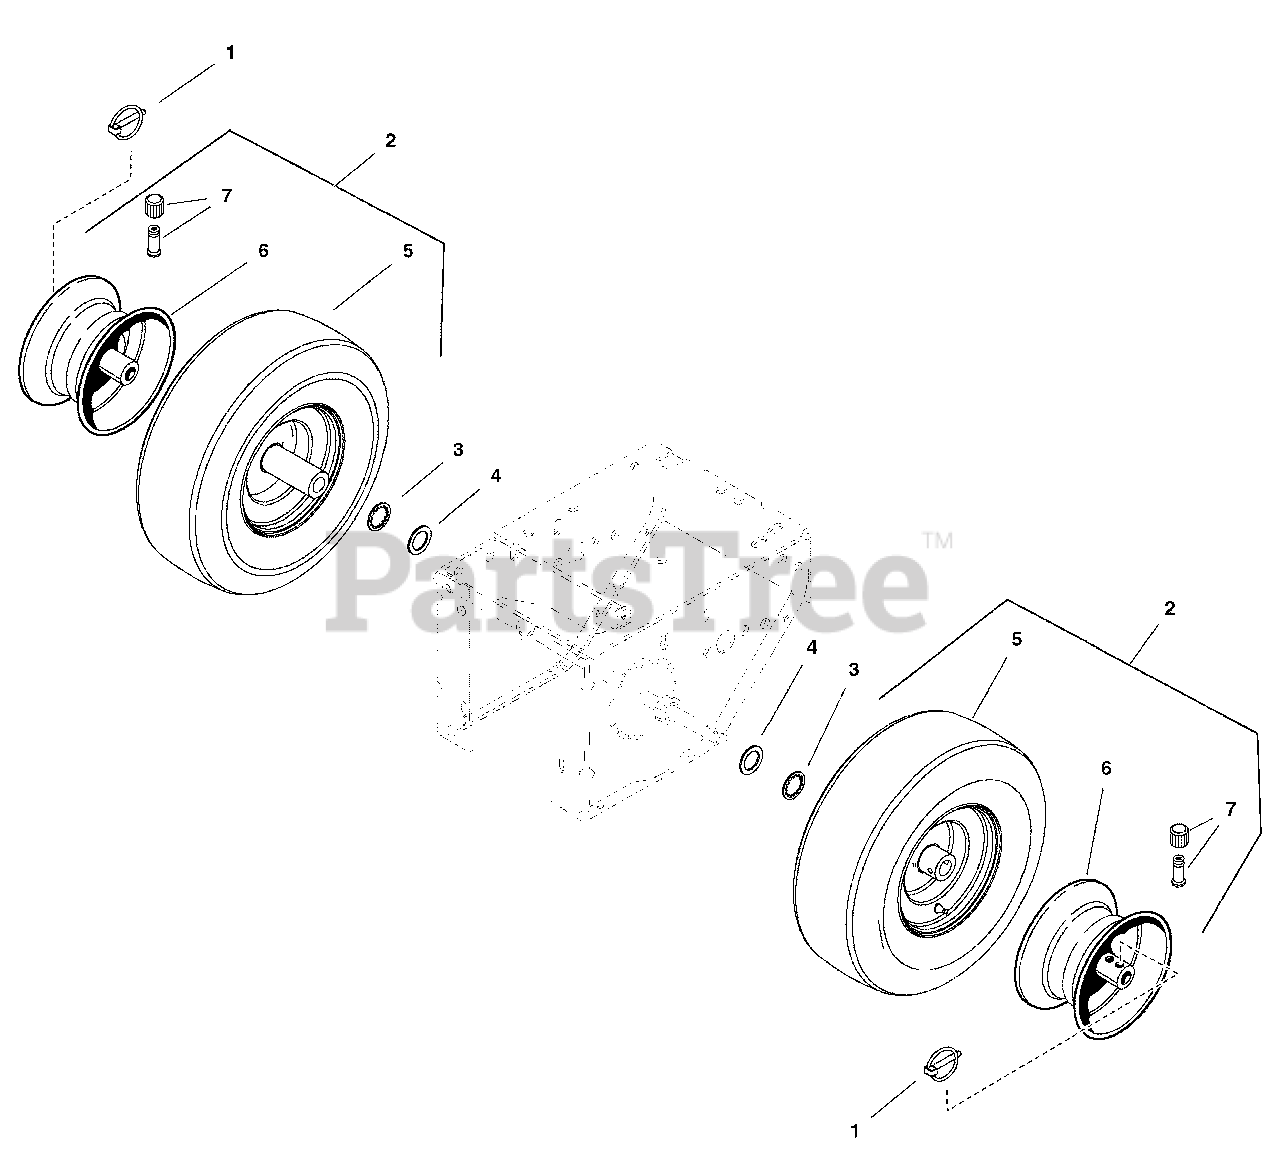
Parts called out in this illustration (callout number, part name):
2	WHEEL & TIRE ASSEMBLY, 13 x 5
3	RETAINING RING, Extension, #75 3/4 Self Lock
4	WASHER, Flat
5	WHEEL, 3.25 Wide 6.00 Diameter
6	TIRE, 13 x 6.00 Snow Hog
7	VALVE STEM & CAP, Air
